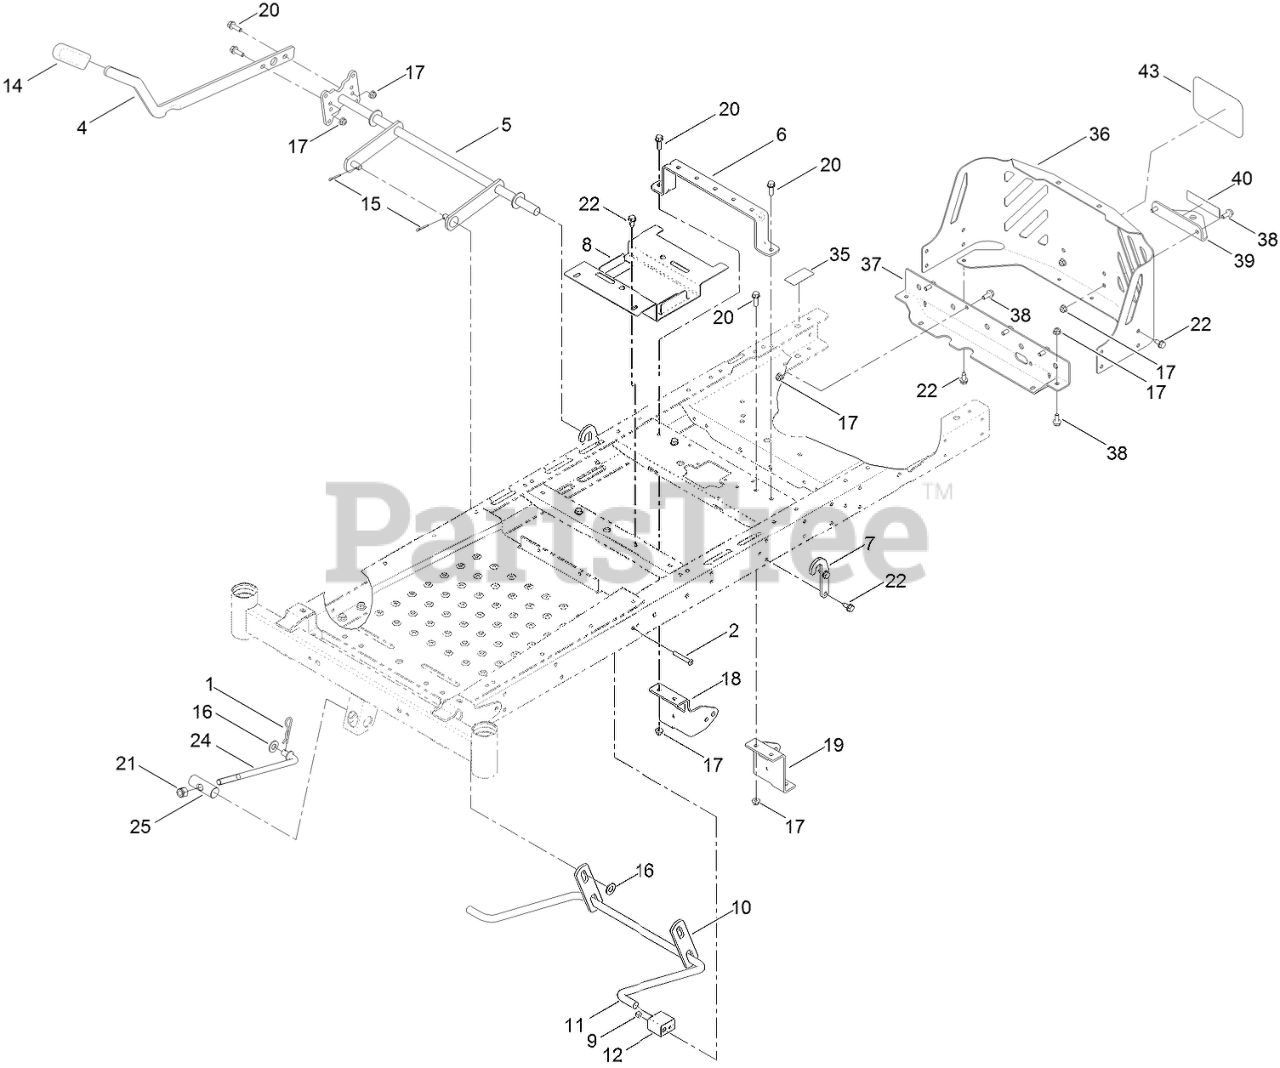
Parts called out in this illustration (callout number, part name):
1	PIN-COTTER
2	SCREW-HSBH
4	LEVER-LIFT
5	LIFT-DECK, NARROW
6	BRACE-SEAT, REAR (NARROW)
7	BRACKET-LIFT
8	BRACKET-BATTERY
9	NUT-LOCK, NI
10	LINK-LIFT
11	ARM-LIFT, REAR
12	BLOCK-PIVOT
14	GRIP-LEVER
15	PIN-COTTER
16	WASHER-FLAT
17	NUT-HF, NI
18	MOUNT-HYDRO, FRONT (RH)
19	MOUNT-HYDRO, FRONT (LH)
20	SCREW-HHF
21	NUT-HEX
22	SCREW-HWHTF
24	ROD-MOUNT, DECK
25	PIN-PIVOT
35	DECAL-BYPASS
36	GUARD-ENGINE, NARROW
37	CROSSMEMBER-REAR, NARROW
38	SCREW-HHF
39	BRACKET-HITCH
43	DECAL
